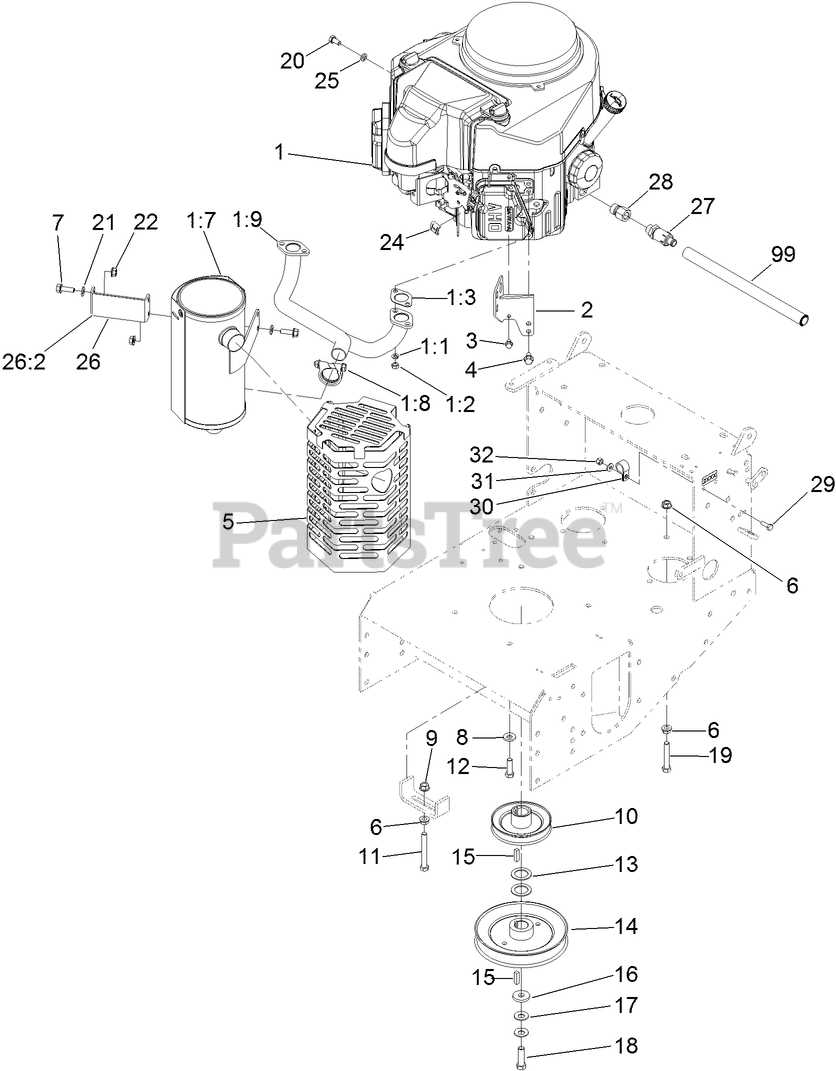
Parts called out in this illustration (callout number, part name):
1:1	WASHER-LOCK
1:3	GASKET-EXHAUST
1:7	MUFFLER-ENGINE
1:8	CLAMP-MUFFLER
1:9	MANIFOLD-EXHAUST
2	BRACKET-MUFFLER
3	SCREW-HHF
4	SCREW-HHF
5	MUFFLER SHIELD ASM
6	NUT-HHF, WHIZ
7	SCREW-HHF
8	WASHER-BELLEVILLE
9	NUT-HF
10	PULLEY
11	SCREW-HH
12	SCREW-HH
13	WASHER-SPACER
14	PULLEY
16	WASHER
17	WASHER-SPRING
18	SCREW-HH
19	SCREW-HH
20	SCREW-HH
21	WASHER-SPRING
22	NUT-HF, LOCK
24	CLAMP-CABLE
25	WASHER-LOCK
26	MUFFLER BRACKET ASM
26:2	FOIL-SHIELD, BRACKET
27	VALVE-DRAIN, OIL
28	Adapter
29	SCREW-HH
30	CLAMP-CABLE
31	WASHER-FLAT
32	NUT-LOCK, NI
99	HOSE-DRAIN, OIL
